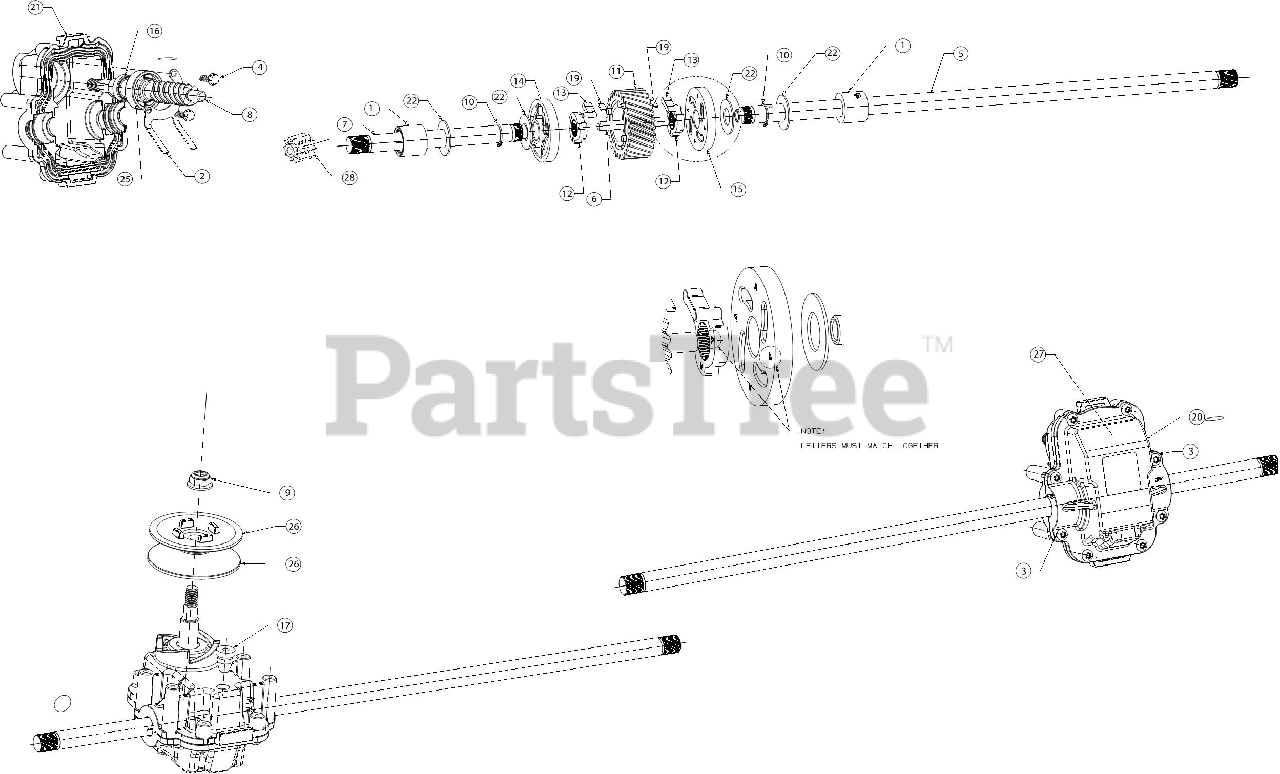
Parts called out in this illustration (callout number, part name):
1	BEARING ASSEMBLY
2	SPRING PLATE
3	SCREW .159 X .610
4	SCREW .159 X .43
5	AXLE SHAFT (RH)
6	PIN
7	AXLE SHAFT (LH)
8	WORM SHAFT
9	FLANGE LOCK NUT 5/16-18
10	SNAP RING FOR .500
11	HELICAL GEAR
12	HUB
13	DRIVE ARM
14	DRAG PLATE (LH)
15	DRAG PLATE (RH)
17	OIL PLUG
18	THREE BOND SEALANT
19	MAGNET
20	LOWER HOUSING
21	UPPER HOUSING
22	FLAT WASHER .508X1.000X.040
23	TRANSMISSION OIL
24	GREASE
25	BALL BEARING
26	HALF PULLEY 2.50 OD
27	TRANSMISSION COVER
28	SPUR GEAR 9T
